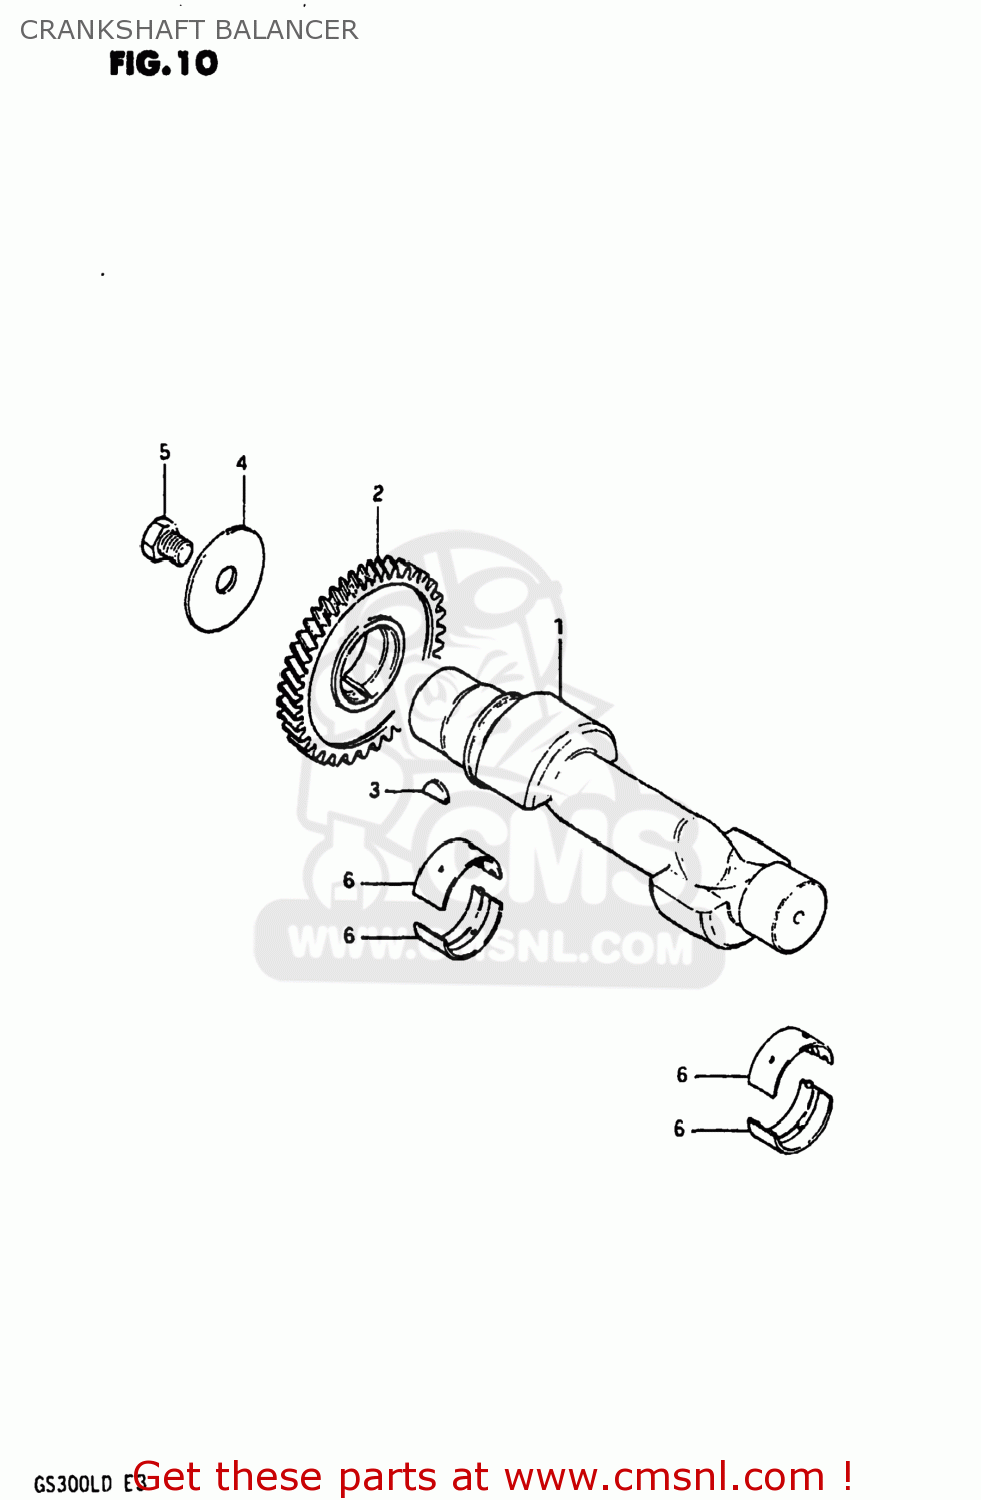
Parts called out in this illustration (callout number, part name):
1	BALANCER,CRANKSHAFT
2	GEAR,CRANK BALANCER
3	KEY 4MM
4	WASHER(12X50X3)
5	BOLT
6	METAL CRANKSHAFT (BROWN)
